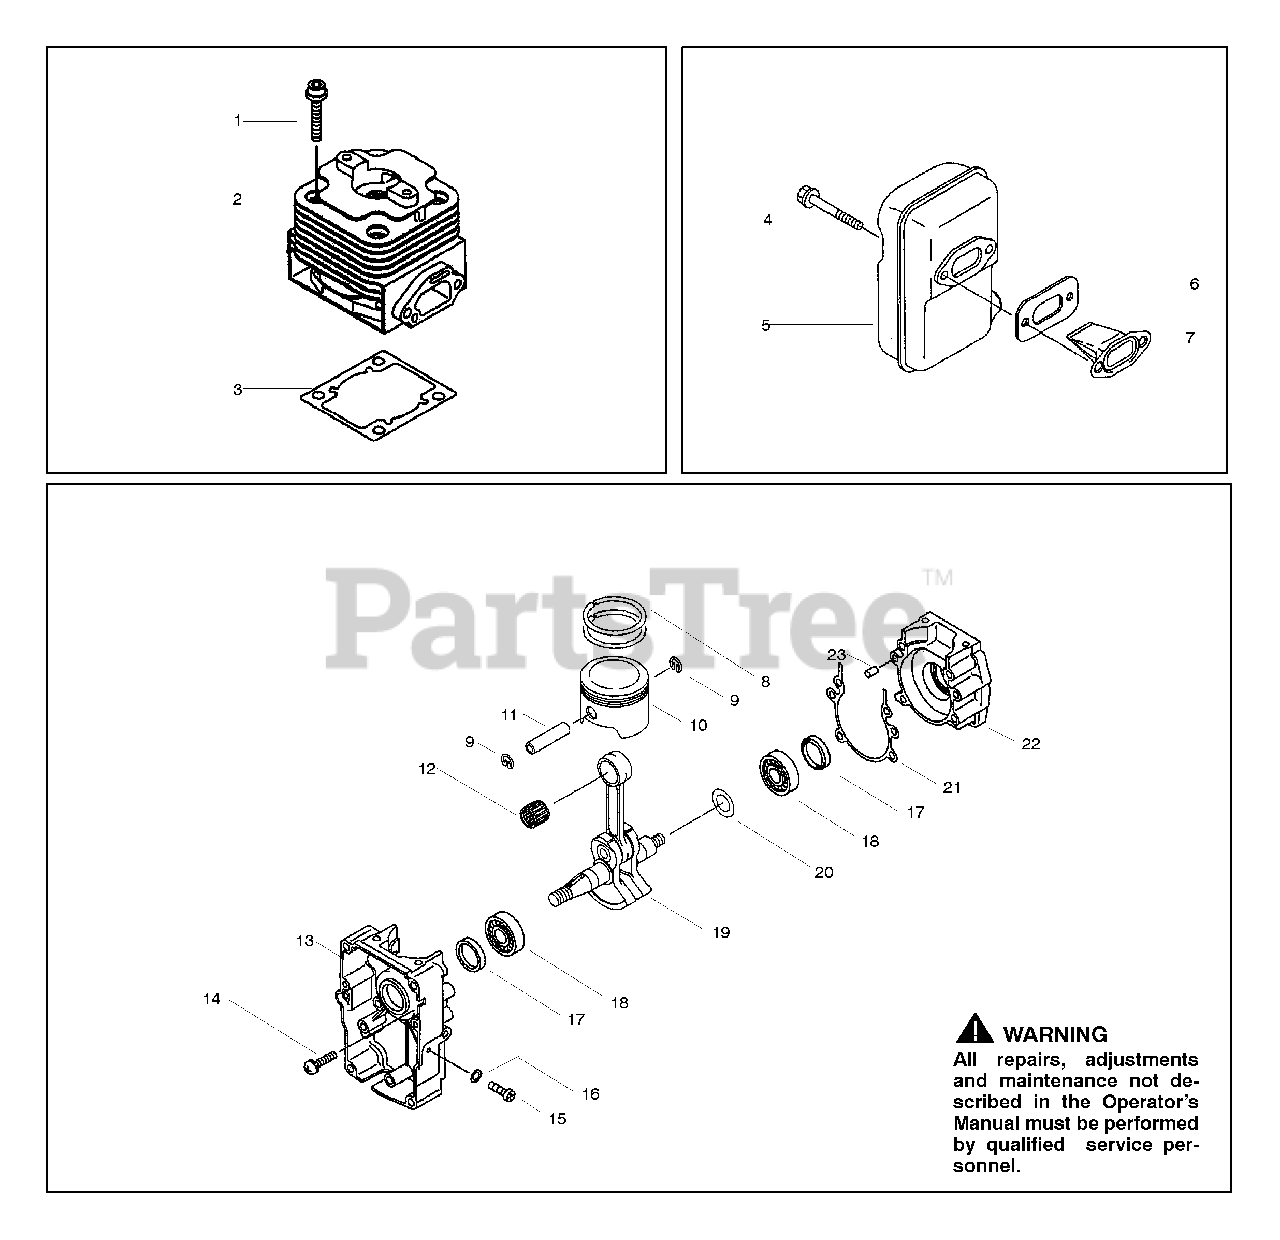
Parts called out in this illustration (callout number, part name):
2	Cylinder-Engine
3	Gasket-Cylinder
4	Bolt 6x65
5	Muffler-Comp.
6	Gasket-Muffler
7	Arrester-Spark
8	Ring-Piston Set
9	Ring-Snap
10	Piston-Engine
11	Pin-Piston
12	Bearing-Needle
13	Crankcase
14	Screw-Pan-WS
15	Screw-Pan
17	Seal-Oil
18	Bearing-Ball 6202C3
19	Assy-Crankshaft
20	Shim-T=0.10
20	Shim-T=0.20
20	Shim-T=0.40
20	Shim-T=0.60
21	Gasket-Crankcase
22	Crankcase
23	Pin-Dowel
